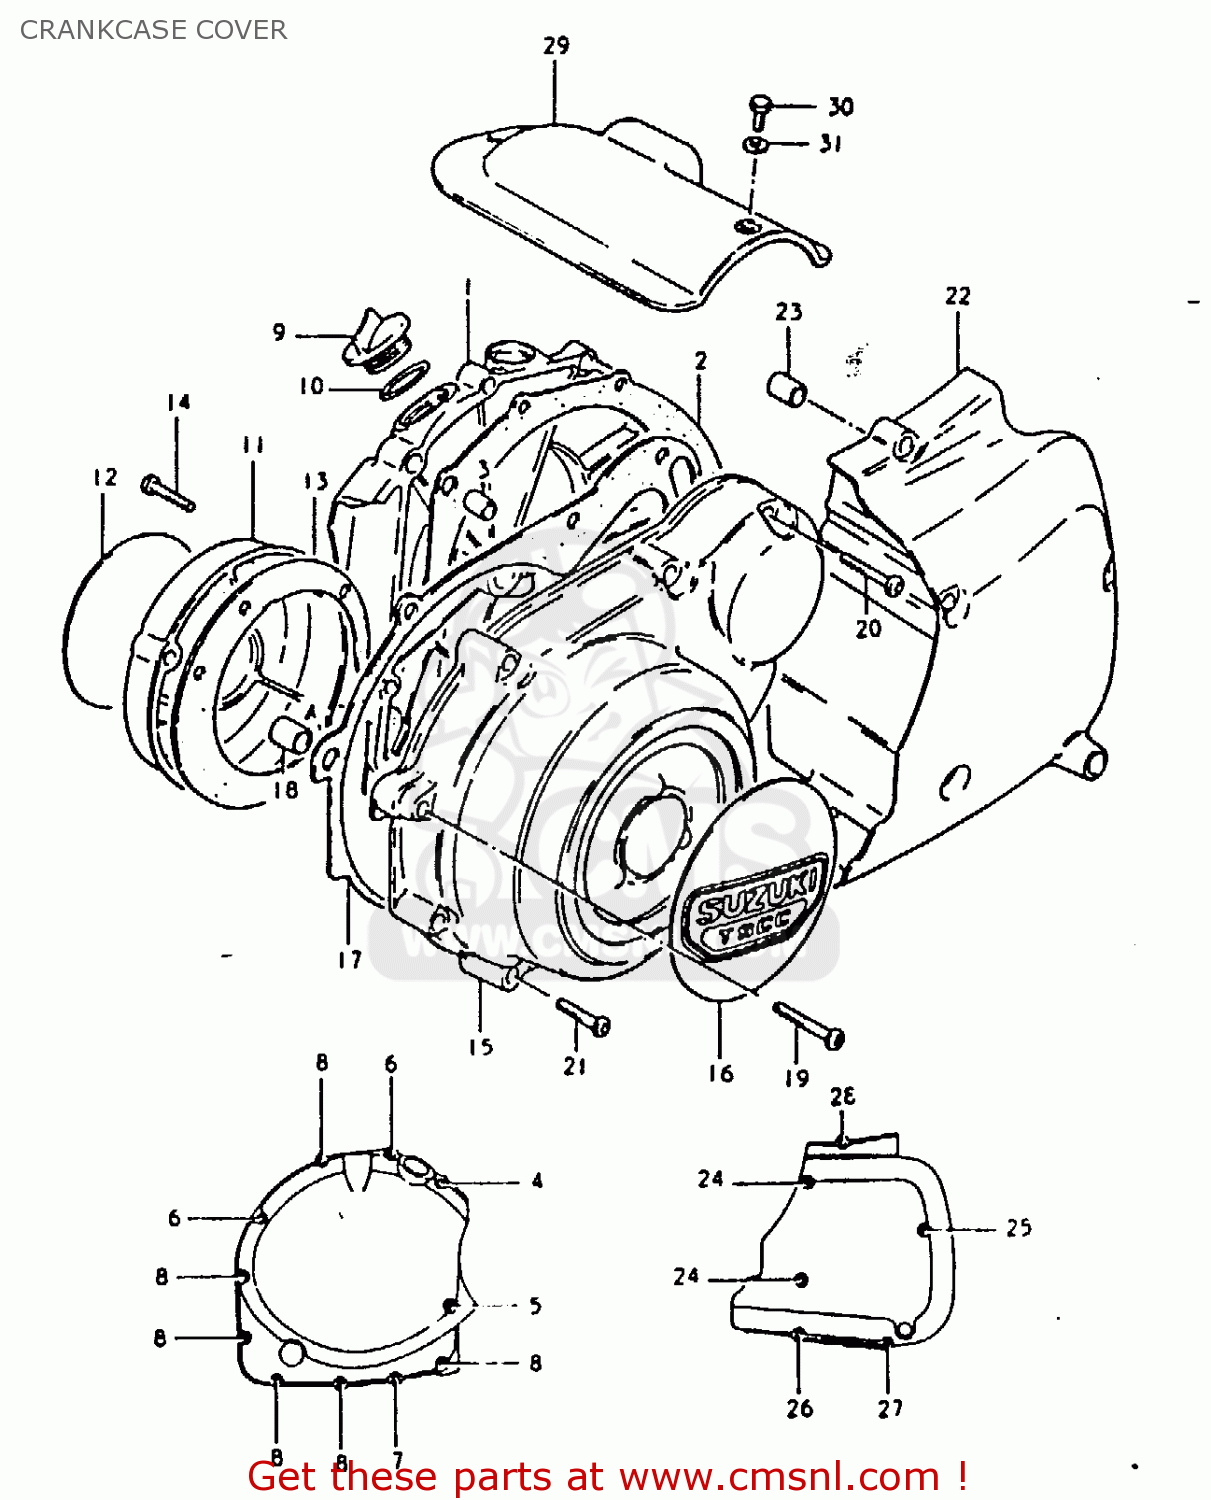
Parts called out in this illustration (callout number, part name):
1	COVER,CLUTCH
2	GASKET,CLUTCH COVER (MCA)
3	PIN
4	SCREW
5	SCREW (6X35)
6	SCREW 6X30
7	SCREW
8	SCREW
9	CAP
10	O RING(D:2.2,ID:32)
11	COVER,CONTACT BREAKER
12	EMBLEM
13	GASKET,CONTACT BREAKER COVER (NAS)
14	SCREW
15	COVER
16	EMBLEM,MAGNETO COVER
17	GASKET,MAGNETO COVER (MCA)
18	PIN
19	SCREW (6X45)
20	SCREW
21	SCREW 6X30
22	COVER,SPROCKET
23	PIN
24	SCREW (6*95)
25	SCREW 6X85
26	SCREW 6X70
27	SCREW
28	SCREW 6X30
29	COVER,STARTER MOTOR
30	BOLT
31	WASHER
